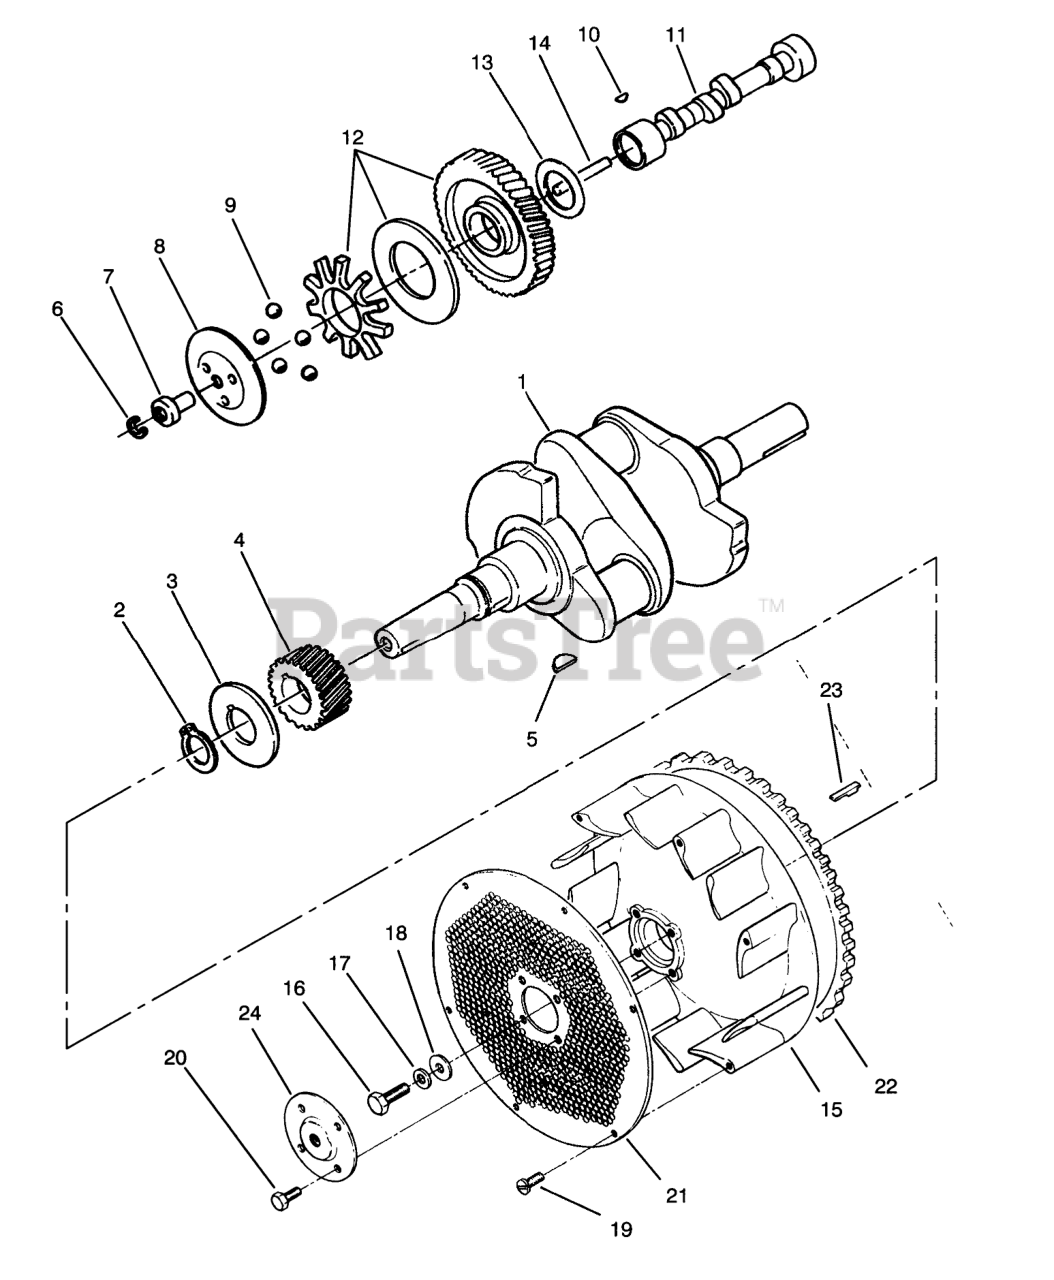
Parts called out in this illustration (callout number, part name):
1	CRANKSHAFT
3	WASHER
7	HUB-GOVERNOR CUP
8	CUP-GOVERNOR
9	BEARING
11	CAMSHAFT (16&18HP)
12	GEAR ASM
13	WASHER-THRUST
14	PIN-CENTER
15	Flywheel-w/Ring Gear
16	SCREW
17	Washer
18	WASHER-FLAT
19	Bolt
20	HX HD LOCK CAPSCREW
21	Screen
23	Key
24	LIFTING-BRKT (ZINC)
